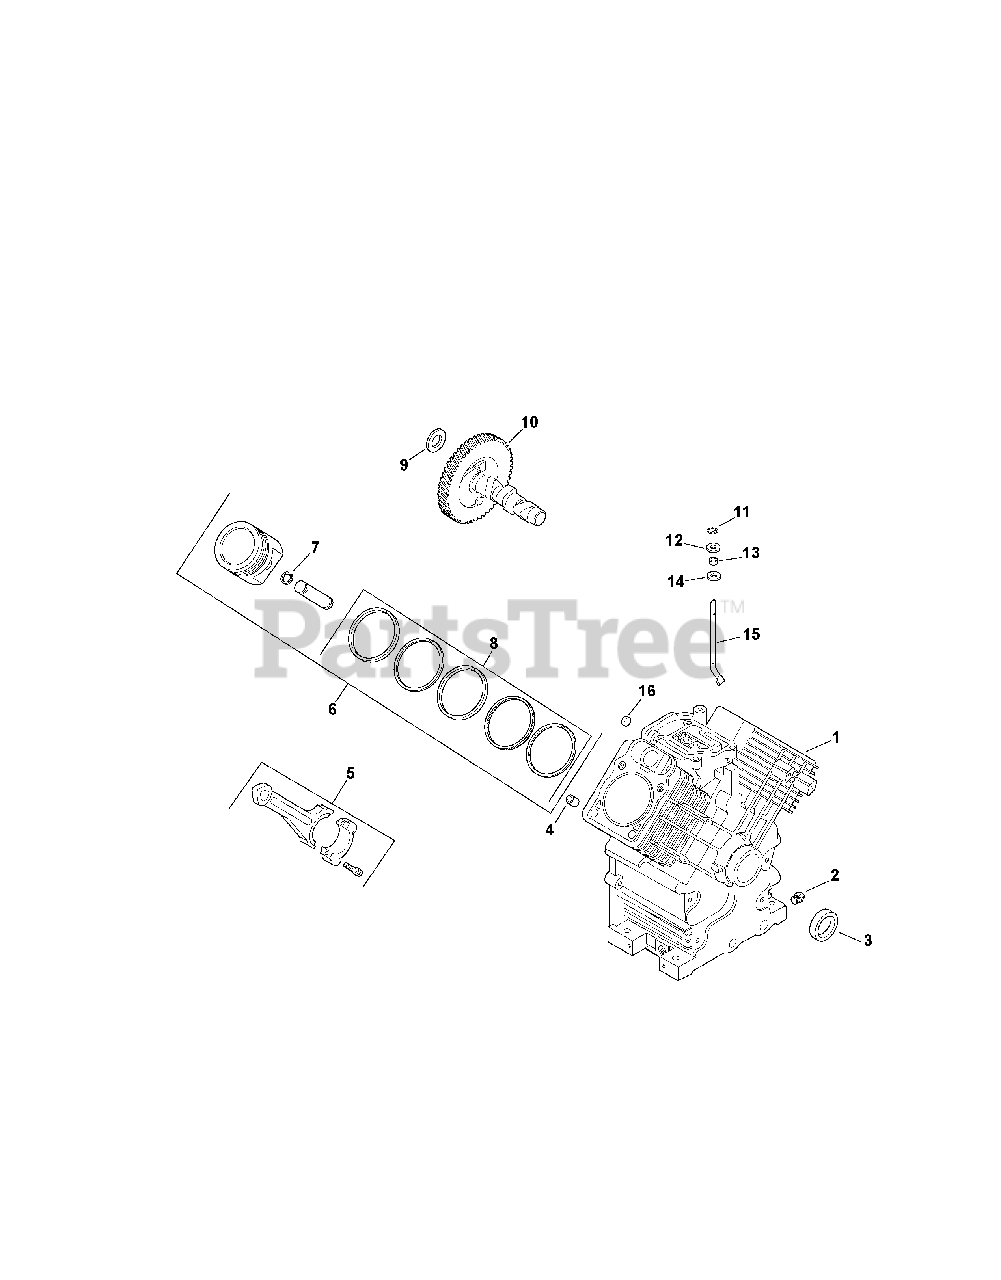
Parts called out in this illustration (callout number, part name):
2	Plug, hex. head 3/8" (2)
3	Seal, front oil
4	Pin, locating (6)
5	Connecting Rod (Std.) (2)
6	Piston w/Ring Set (Std.) (2) Includes 7,8)
7	Retainer, piston pin (4)
8	Ring Set (Std. & .08) (2)
9	Shim, camshaft (A.R.) red
10	Camshaft
11	Retainer, ring
12	Washer, plain 9 mm
13	Seal, governor cross shaft
14	Washer, plain 1/4"
15	Shaft, governor cross
16	Plug, cup
